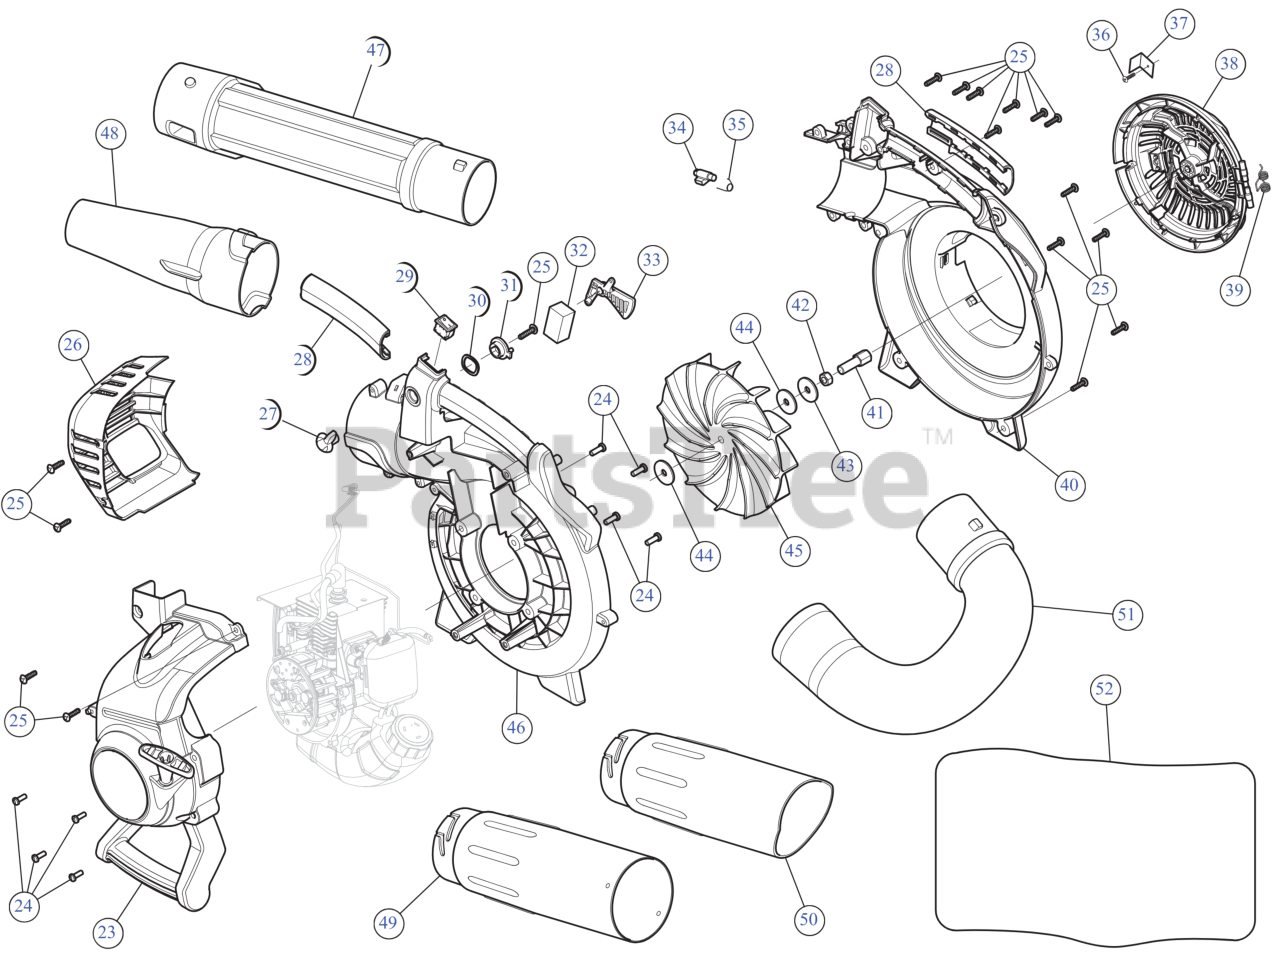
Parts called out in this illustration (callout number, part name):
23	STARTER HOUSING ASSEMBLY
24	SCREW:10-32X.562:#8P
25	SCREW 8-16 x 3/4
26	MUFFLER COVER
27	TRIGGER LOCK OTR
28	ANDLE GRIP ASSEMBLY
29	SW, MOMENTARY ON/O
30	WASHER WAVEY
31	TRIGGER LOCK INR
32	AIR FILTER
33	THROTTLE TRIGGER
34	LATCH TUBE
35	SPRING LATCH
36	SCREW-10-9 x .50
37	DOOR LOCK SC
38	INTAKE COVER BLK
39	SPRING
40	IMPELLER HOUSING OTR
41	ADAPTER STARTER
42	HEX NUT CENTER
43	LOCK WASHER
44	WASHER FLAT
45	IMPELLER
46	IMPELLER HOUSING INR
47	UPPER TUBE
48	NOZZLE BKPK CUB
49	UPPER VAC TUBE SCBLO
50	TUBE, LOWER VACUUM (ELEC BLWR-
51	ELBOW TUBE
52	VAC BAG SCBLO
